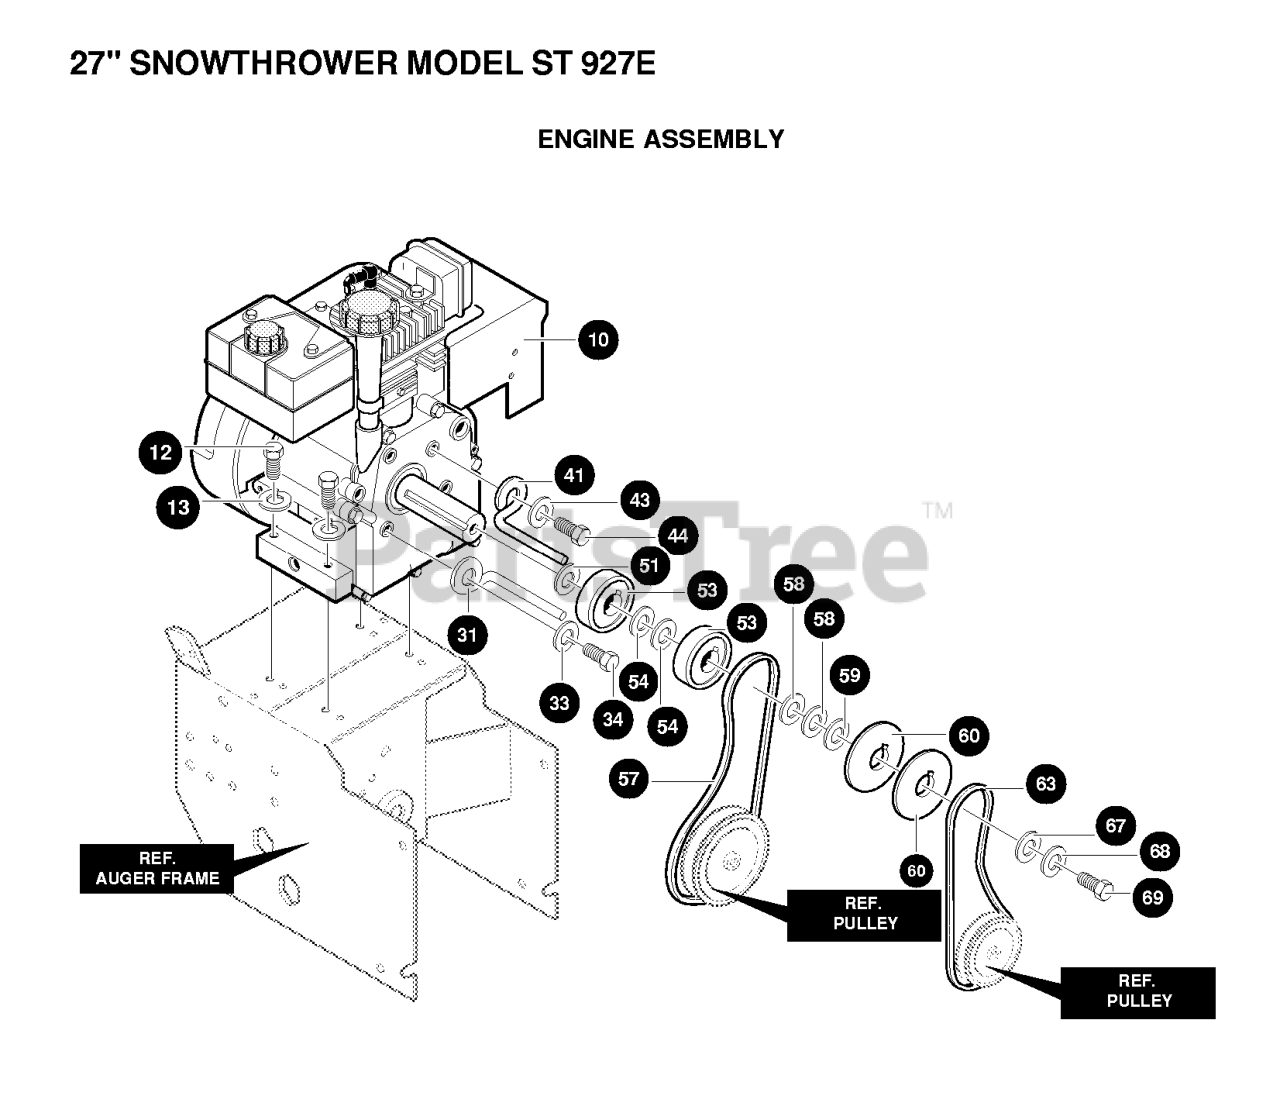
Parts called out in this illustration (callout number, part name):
12	SCREW, 5/16-18
13	WASHER, HVSPTLK .328X.60X
31	BELT GUIDE
33	WASHER, HVSPTLK .328X.60X
41	BELT GUIDE
43	WASHER, HVSPTLK .328X.60X
57	BELT 1733324SM
59	Spacer, Slev .753 x 1.12 x .38
60	PULLEY, ENGINE
63	BELT, V4L 38.2 LG AUG DRIVE
68	WASHER, REGSPTLK.393X.68X
69	SCREW, 3/8-24X1.00 NYLHHC
